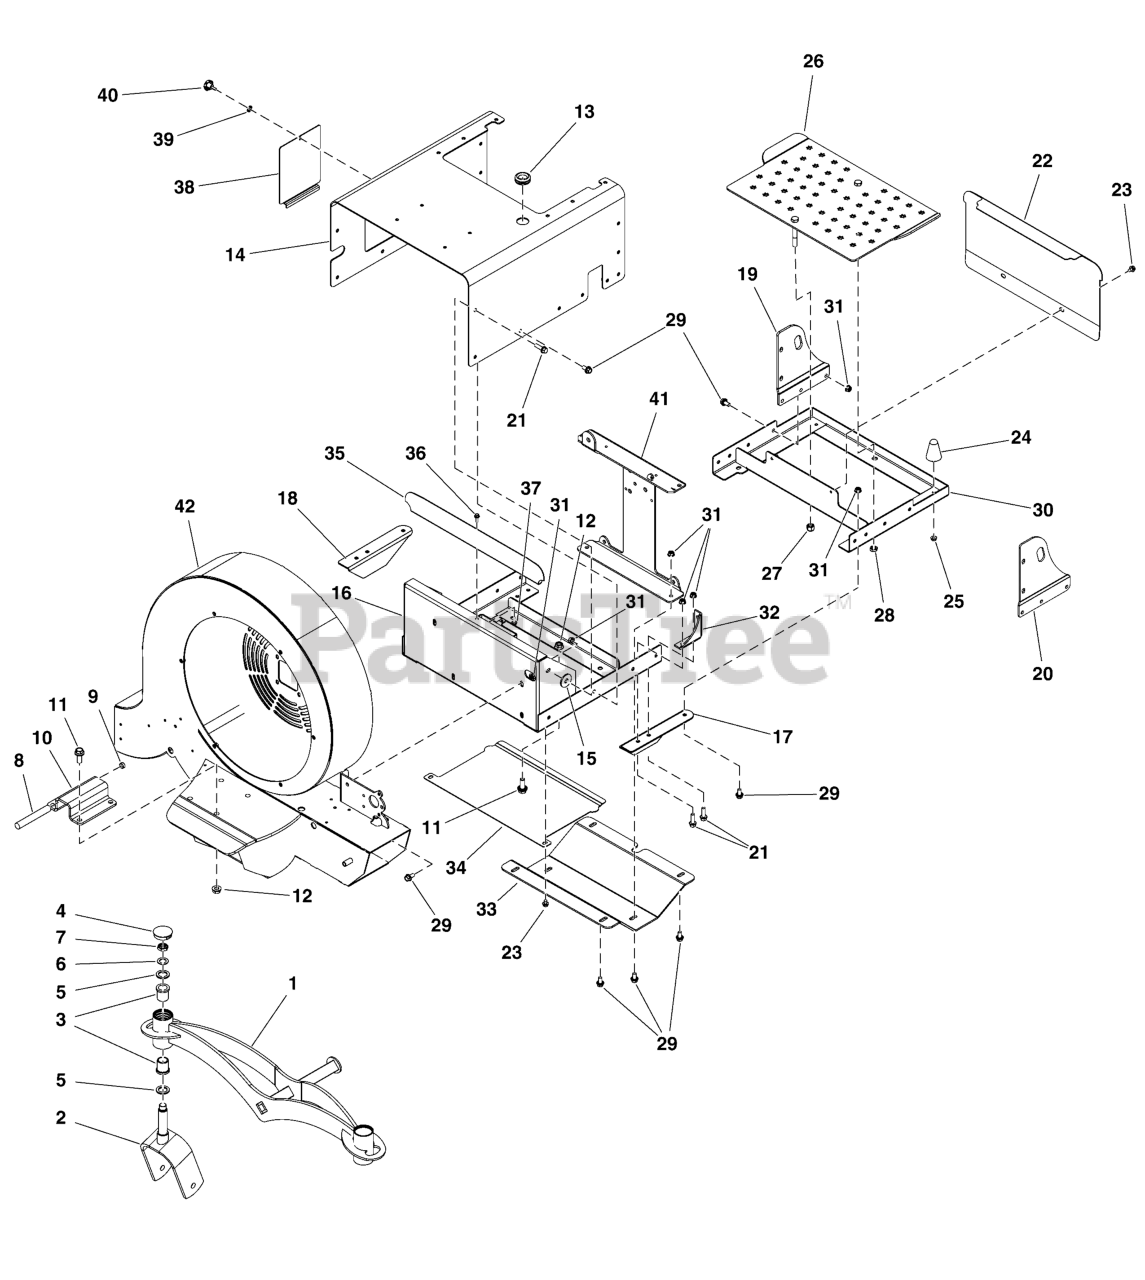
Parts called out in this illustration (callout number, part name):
2	WELD, CASTER YOKE, X3 - RED
3	BUSHING, FLANGE
4	CAP, GREASE, PLASTIC
5	WASHER, 1 X 10GA, MACH, CZ
6	WASHER, 3/4 X 14GA, MACH, CZ
7	NUT, 3/4-10, NYLOCK JAM, CZ
8	CORD, RUBBER
9	RUBBER BAND
10	PLATE, FRONT END TORSION C - RED
11	BOLT, 1/2-13 X 1-1/4, FLANGE, CZ
12	NUT, 1/2-13 SERRATED FLANGE, CZ
13	GROMMET, RUBBER
14	WELD, MOTOR BOX - RED
15	SPACER, MOTOR BOX 10GA
16	WELD, X3 FRONT CHASSIS - BLK
17	BRACKET, BOTTOM CHASSIS LEFT - BLK
18	BRACKET, BOTTOM CHASSIS RIGHT - BLK
19	PLATE, TIE DOWN RH - RED
20	PLATE TIE DOWN LH - RED
21	BOLT, 3/8-16 X 1-1/4, FLANGE, GD 5, CZ
22	PLATE, TOE KICK, FB2000 - RED
23	SCREW, 5/16-18 X 1/2, SLF TPNG, CZ
24	BUMPER, RUBBER, 5/16-18
25	NUT, 5/16-18 HEX SERRATED FLANGE (SMALL)
26	WELD, PLATFORM, BLWR - BLK
27	NUT, 1/2-13 HEX NYLON LOCK
28	NUT, NTE, 1/2-13, CZ
29	BOLT, 3/8-16 X 3/4, FLANGE, CZ
30	WELD, X3 REAR CHASSIS - BLK
31	NUT, 3/8-16, FLANGE, SERRATED UNDER HEAD
32	WELD, TRANS 90 DEG MOUNT BRACKET - BLK
33	PLATE, SKID - BLK
34	GUARD, LOWER DEBRIS - BLK
35	GUARD, FORWARD DEBRIS - BLK
36	BOLT, 1/4-20 X 3/4, FLANGE, CZ
37	NUT, 1/4-20 HEX SERR. FLANGE
38	PLATE, BATTERY DOOR - RED
39	WASHER, INT / EXT TOOTH, CZ
40	KNOB, 1/4-20 X 1/2 CAP SCREW
41	WELD TRANS I-BEAM - BLK
42	WELD, BLOWER HOUSING , X3 - RED
